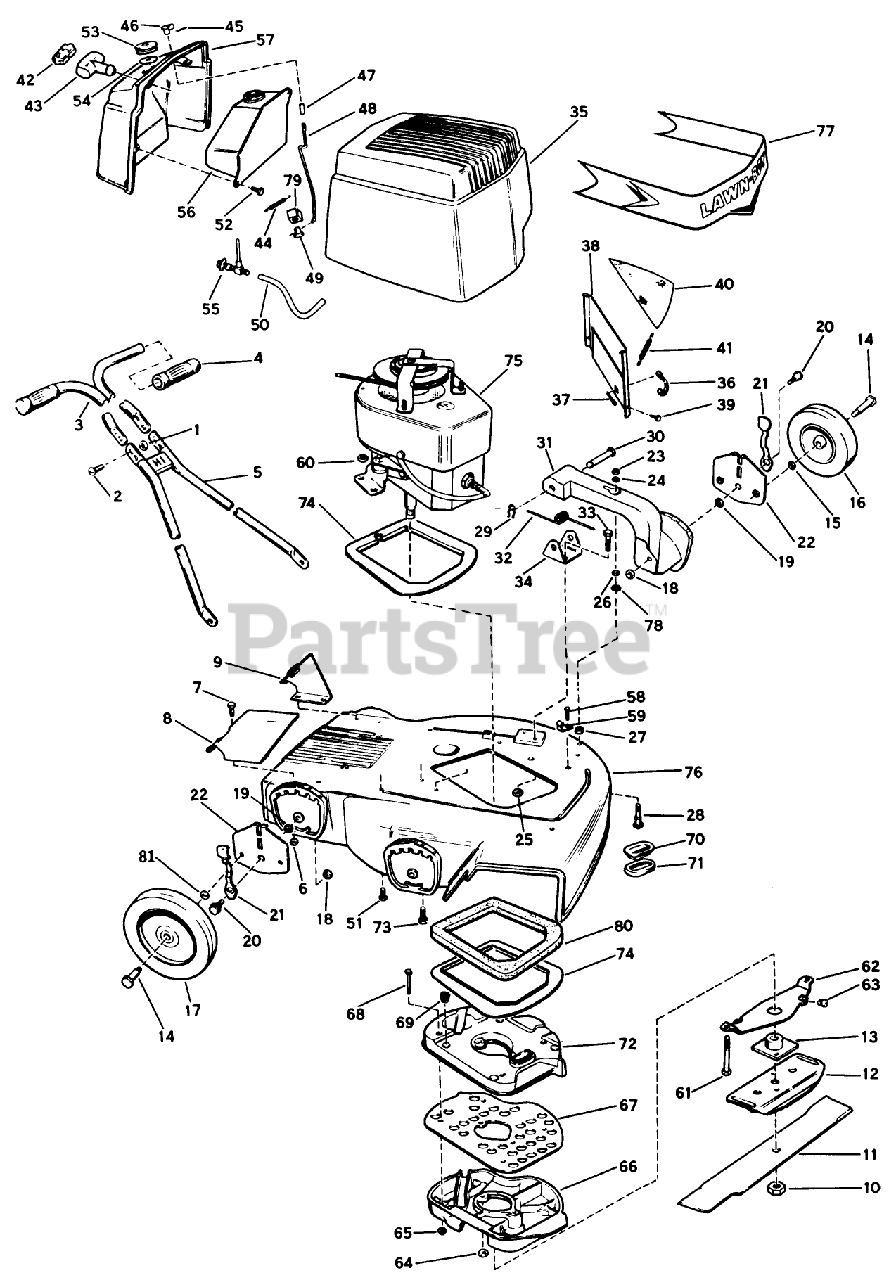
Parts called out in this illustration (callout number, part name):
1	STOP NUT
10	NUT-BLADE
13	PLATE AND COLLAR ASM
14	BOLT WHEEL
23	STOP NUT
24	Washer-Level Ride, Fiber
25	STOP NUT
26	Washer-Level Ride Arm
27	Jam Nut
28	Bolt-Level-Ride Arm
29	Hair Pin-Level Ride Arm
30	Pin-Level Ride Arm
32	Spring-Level Ride Arm
33	Screw-Level-RideArm Bracket
34	Bracket-Level Ride Arm
38	Shield Sound Trap
39	Screw-Thread Cutting
40	Screen-Sound Trap
45	Cotter Pin-Choke Knob
46	KNOB, CHOKE BAR
48	Rod-Choke
49	Pivot-Choke Rod (Nylon)
52	Screw-Thread Cutting
53	Gas Cap
57	Bonnet-Rear
58	Screw-Thread Cutting
59	Latch-Bonnet
61	Screw-Engine Mtg., Long
62	Bracket-Crankshaft Limit Stop
63	Bumper-Crankshaft Limit Stop
64	Nut-Muffler to Crankcase Studs
65	LOCKNUT E
66	Muffler-Bottom
67	Gasket-Muffler
68	Bolt-Muffler
69	Spring-Muffler
72	Muffler-Top
74	Seal-Dust
76	Housing, 19"
77	Decal-LAWN-BOY
79	Retainer-Choke Rod
80	Gasket-Dust Seal
81	WASHER WROUGHT
